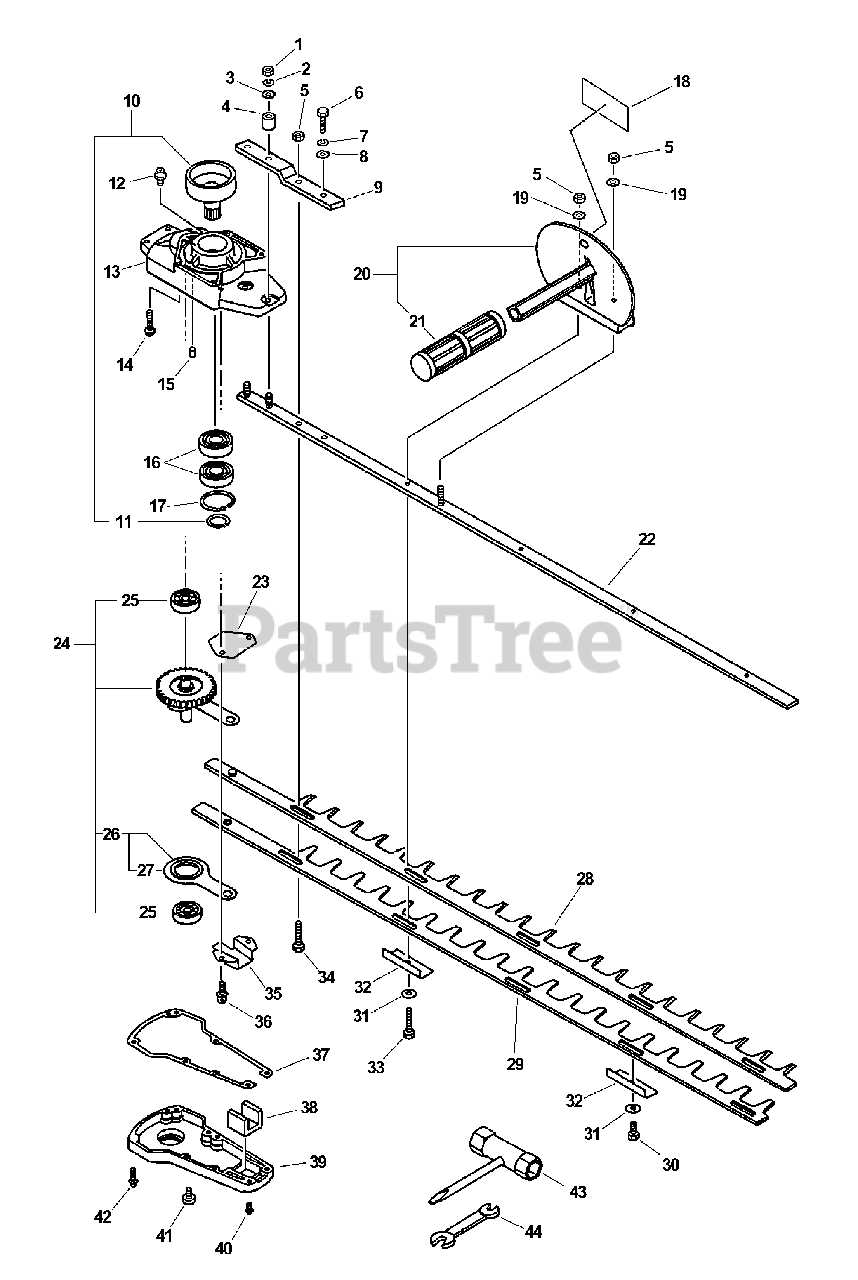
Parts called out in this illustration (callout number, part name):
1	LOCKNUT - 6
2	LOCKWASHER - 6
3	WASHER - 6
4	SPACER
5	LOCKNUT - 6
6	BOLT - 6X10
7	LOCKWASHER - 6
8	WASHER - 6
9	BRACKET, ANGLE
10	DRUM, CLUTCH
11	RING, RETAINING - 16
12	FITTING, GREASE
13	CASE, GEAR
14	SCREW - 5X30
15	PIN - LOCATING
16	BEARING, BALL - 6003
17	RING, RETAINING - 35
18	LABEL - CAUTION
19	WASHER - 6
20	HANDLE ASSY - FRONT
21	GRIP, HANDLE
22	SUPPORT, BLADE
23	PLATE, GUIDE
24	GEAR ASSY
24	GEAR SHAFT ASSY
25	BEARING, BALL - 6200
26	CONNECTING ROD ASSY
27	BEARING, NEEDLE
28	BLADE - UPPER
29	BLADE - LOWER
30	BOLT
31	WASHER
32	INSULATOR
34	BOLT - 6
35	GUIDE
35	GUIDE, BLADE
36	SCREW - 5X14
37	GASKET, GEAR CASE
38	SEAL, FELT
39	LID, GEAR CASE
40	SCREW - 4X14
41	BOLT - 8X8
42	SCREW - 4X22
43	T-WRENCH - 13X19mm
44	SPANNER - 8X10mm
